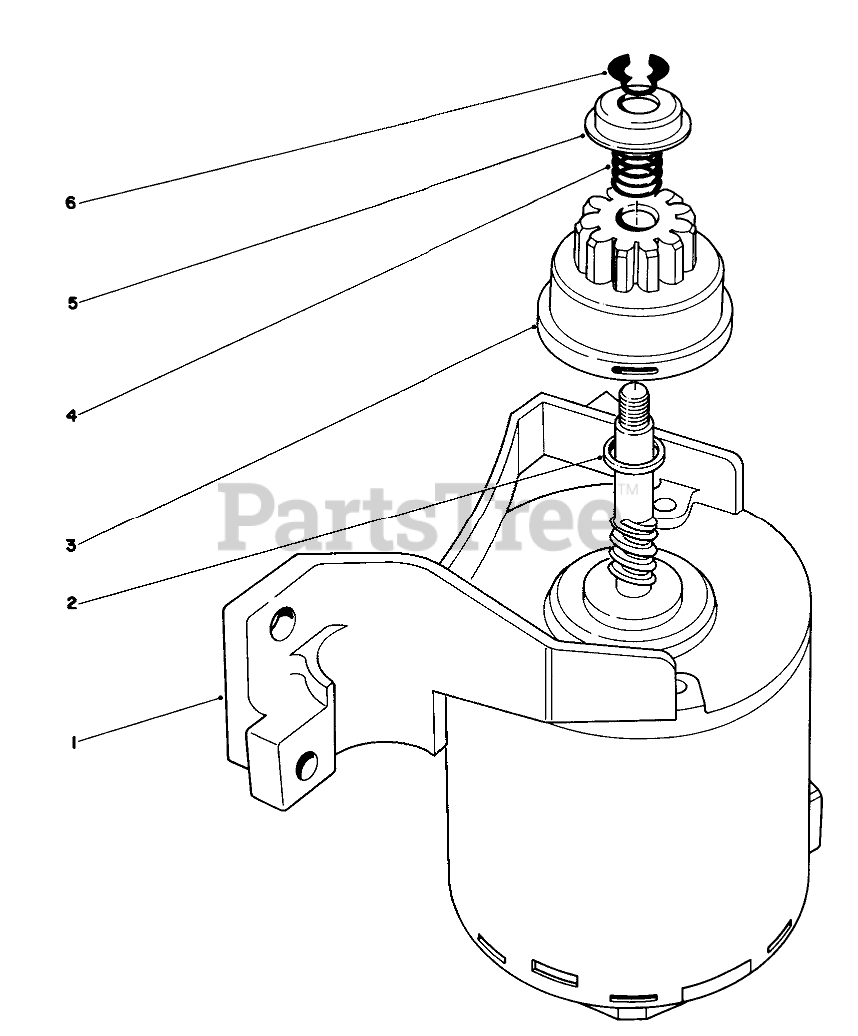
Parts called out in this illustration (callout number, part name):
1	BRKT END FRAME
2	Spacer
3	PINION ASM
4	COMPRESSION SPRING
5	PINION STOP
6	RING-RETAINING
